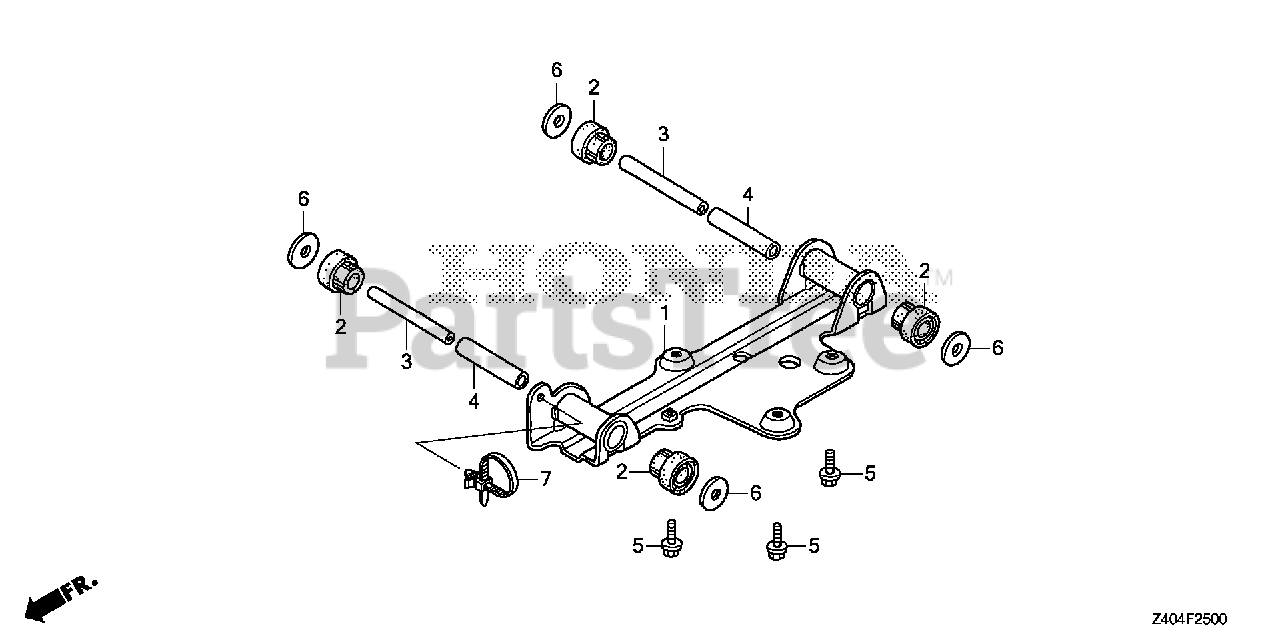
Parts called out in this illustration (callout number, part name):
1	BED, ENGINE
2	INSULATOR, ENGINE BED
3	COLLAR A, INSULATOR
4	COLLAR C, INSULATOR
5	BOLT, FLANGE (6X16) (CT200)
6	WASHER, SPROCKET SETTING
7	STRAP, CABLE (118MM) (BLACK)
